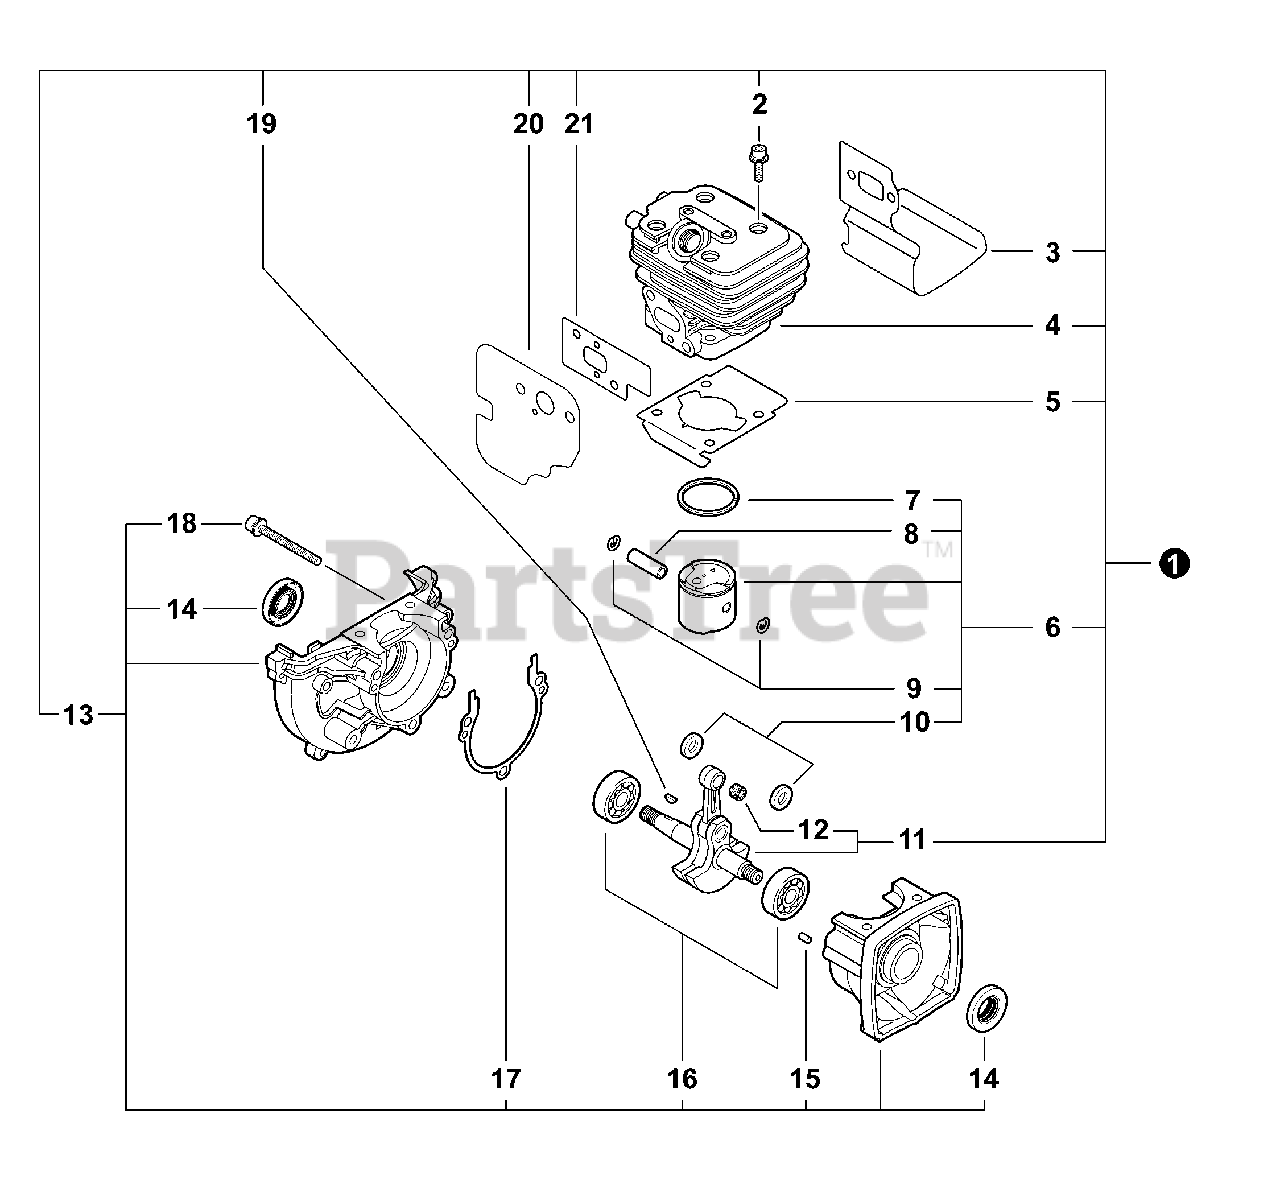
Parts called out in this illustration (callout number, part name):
1	SHORT BLOCK
2	SCREW - 5×25
3	SHIELD, EXHAUST
4	CYLINDER
5	GASKET, CYLINDER
6	PISTON KIT
7	RING, PISTON
8	PIN, PISTON
9	RING, RETAINING
10	SPACER, PISTON
11	CRANKSHAFT ASSY
12	BEARING, NEEDLE - 8
13	CRANKCASE KIT
14	SEAL, OIL
15	PIN, LOCATING
16	BEARING, BALL - 6201
17	GASKET, CRANKCASE
18	SCREW - 5×28
20	GASKET, INTAKE
21	GASKET, INTAKE
